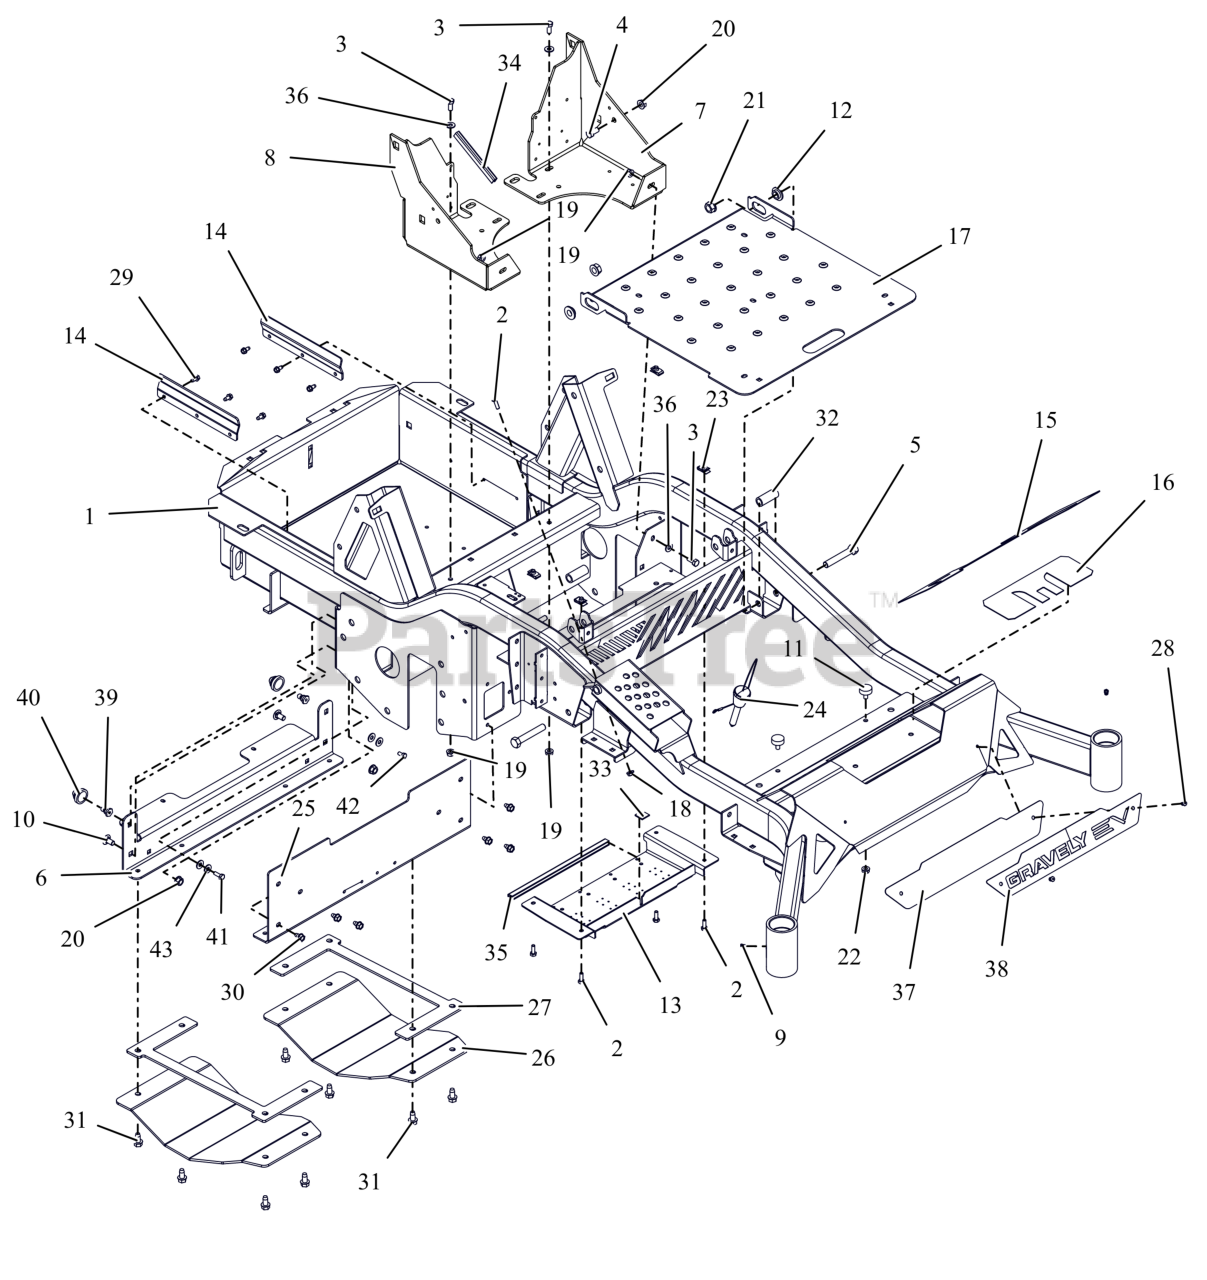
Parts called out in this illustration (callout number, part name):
1	KIT,EV FRAME(LG)W/DECALS-G
2	BLT, HEX .25-20X.75 G5 ZCC
3	BLT,HEX .31-18X.75 G5 ZCC
4	BLT,HEX .38-16X.75 G5 ZCC
5	BLT, HEX .50-13X3.00 G5 ZCC
6	BRKT, SKID PLATE MTG. (RED)
7	BRKT, SUPPORT ROPS -LH (RED)
8	BRKT, SUPPORT ROPS-RH (RED)
9	FTG, .25-28 FLUSH MNT GREASE
10	BLT, RHSSN .38-16X.75 G5 ZCC
11	BUMPER, RUBBER
12	BSHG-FLG .515X.750X.310X1.120
13	COVER, BOTTOM ACCESS -OPEN (RED)
14	DEFLECTOR, BATTERY -EV (RED)
15	GRIP, FRONT
16	GRIP, TAPE FRONT
17	KIT,ACCESS PANEL W/DECALS-RED
18	NUT-LK-CTR-FLG .25-20 ZC120
19	NUT,LK-CTR-FLG .31-18 GF ZCC
20	NUT-LK-CTR-FLG .375-16 GF ZCC
21	NUT-LK-CTR-FLG .500-13 GG ZCC
22	NUT,SPNLK-FLG .31-18 G5 ZCC
23	NUT-RTNR .25-20X.56
24	PIN- MAGNETIC .50X2.70
25	PLATE, FRONT FRAME (RED)
26	PLATE, SKID (BLACK)
27	PLATE, SKID TENSION (BLACK)
28	RIVET, .1875 AL/AL .126-.250
29	SCR-TAP .25-20X.50 HWH ZCC
30	SCR,TAP .312-18X.50 HWH TR ZCC
31	SCR,TAP .375-16X.75 HWH TR ZCC
32	SPACER, .515X.75X1.83
34	STRIP, COWL
35	STRIP, COWL
36	WSHR, FLT .312X.734X.065 ZCC
37	PLATE, BACK - GRAVELY (BLACK)
38	PLATE, LOGO - GRAVELY EV (RED)
39	STUD, BALL FEMALE .250-20 THREAD
40	COUPLING, RUBBER PUSH-IN
41	BLT, HEX .25-20X.75 G5 ZCC
42	BLT,HEX .25-20X.50 G5 ZCC
43	WSHR, FLT .312X.734X.065 ZCC
